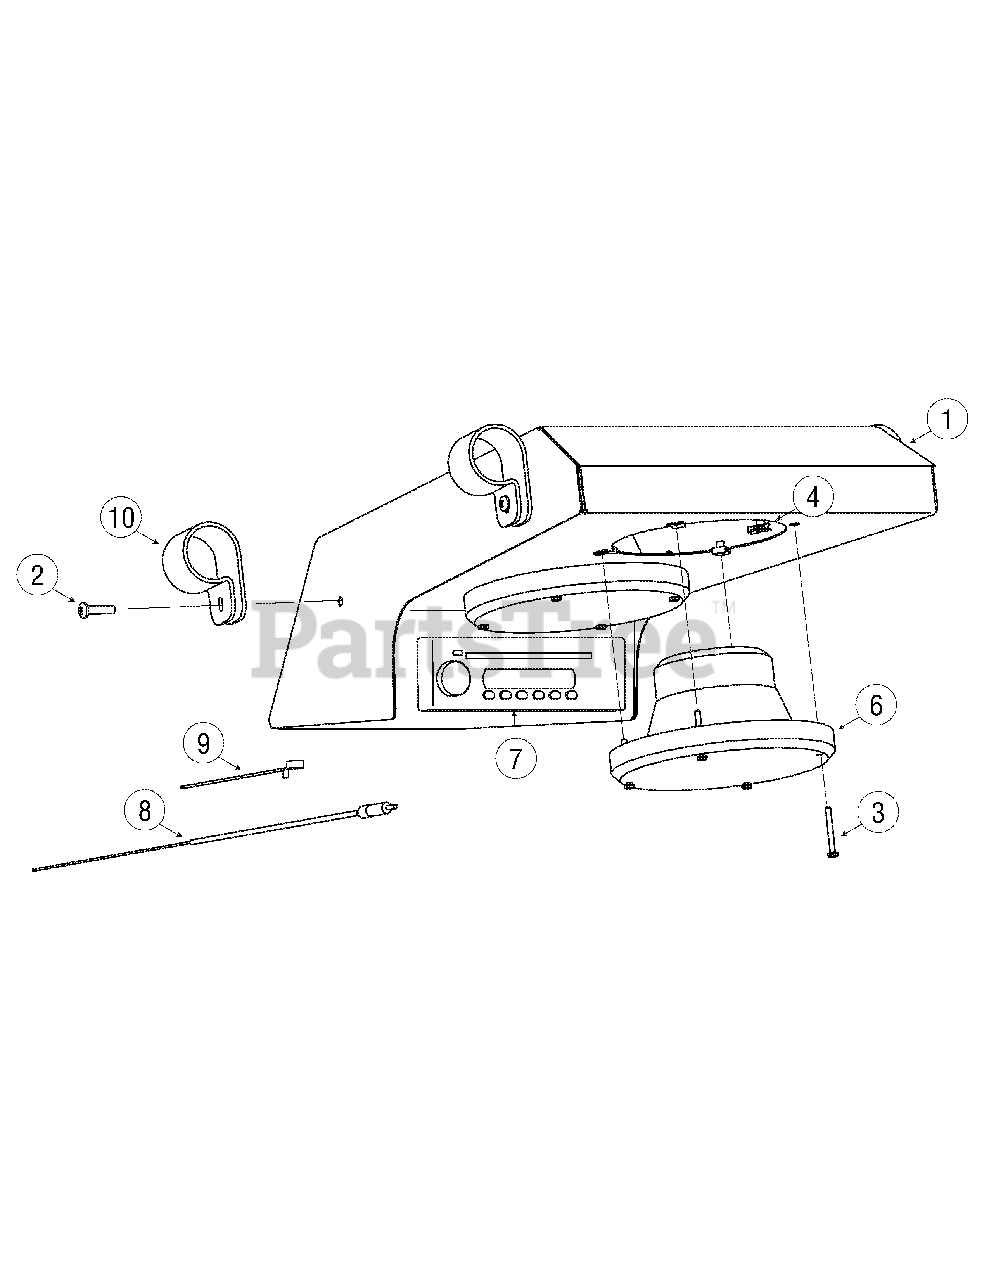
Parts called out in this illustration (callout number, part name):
3	Scr, Mach, #8-32 x 1.500
6	Elec, Speaker, JBL
7	Elec, Radio, JBL
8	Elec, Antenna
9	Tie, Cable
10	Clamp, Tube
